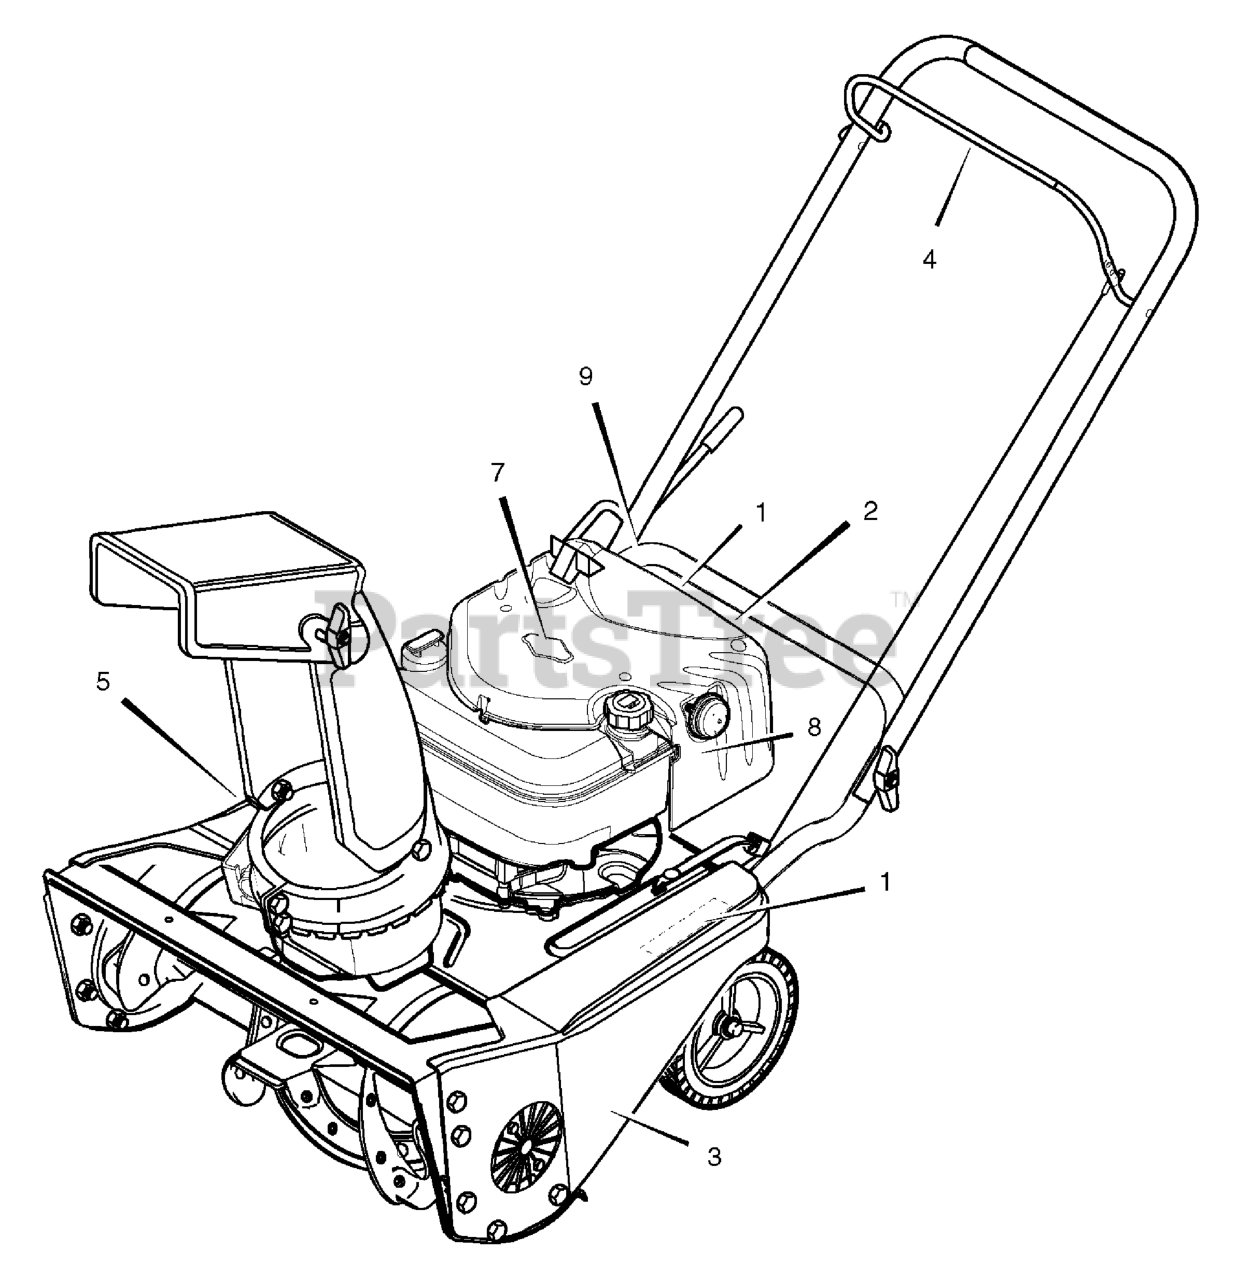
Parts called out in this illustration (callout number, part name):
1	DECAL, Murray 4hp / 21"
2	DECAL, Choke
3	DECAL, Belt Instruction (inside cover)
4	DECAL, Auger Control Lever
5	DECAL, Safety, EN, FR, Danger
7	DECAL, Briggs & Stratton
8	DECAL, Primer Bulb
9	Decal, Handle Protector
